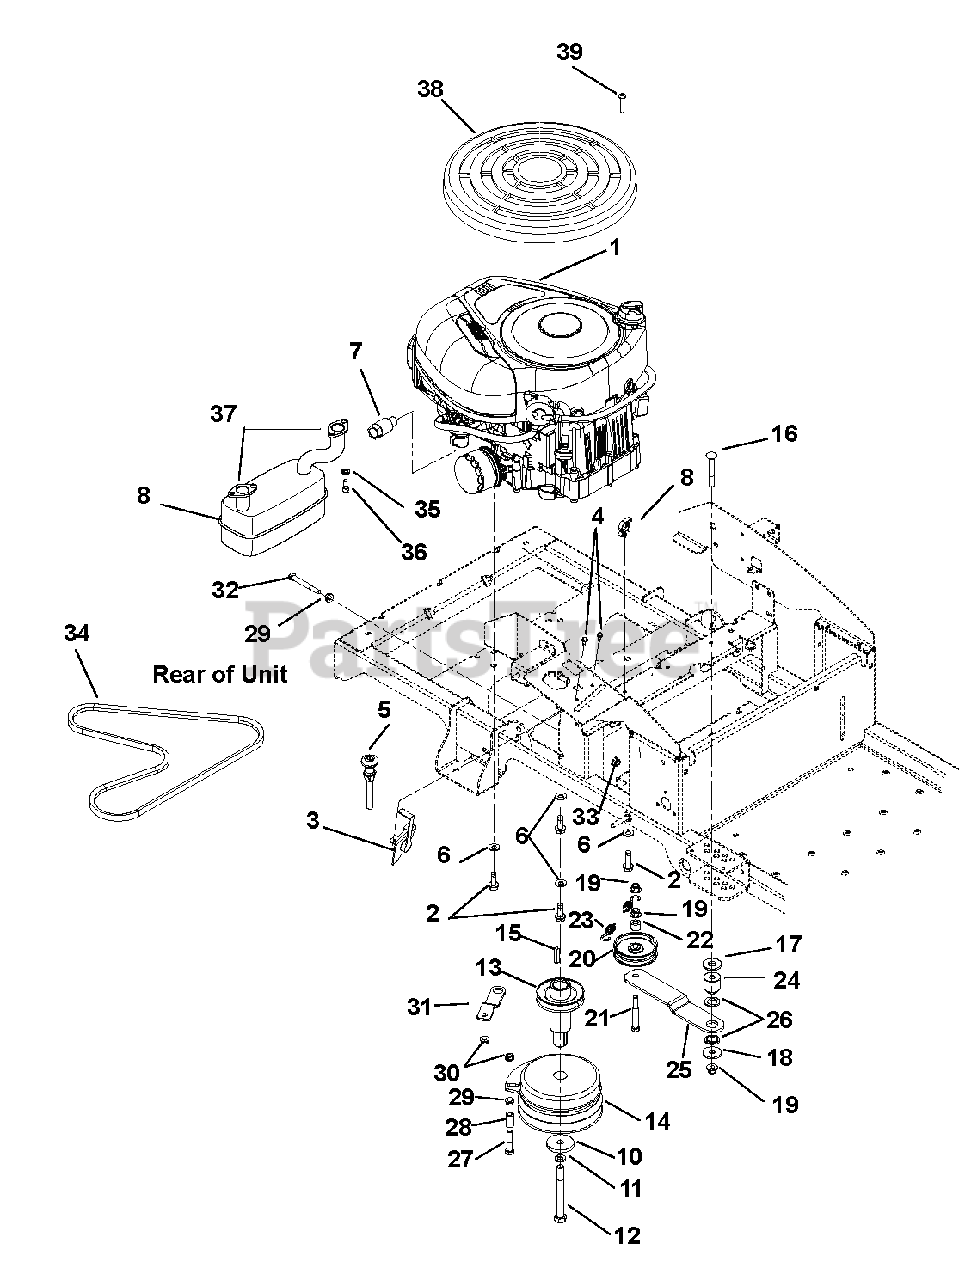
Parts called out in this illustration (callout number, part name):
1	ENGINE, 16HP V-TWIN CE
2	@SCR-TAP .38-16X1.00 HWH TR YZ
3	CABLE, THROTTLE
4	@SCR-TAP 10-24X.50 HWH TR YWZC
5	CABLE, CHOKE (SNAP IN)
6	@WSHR-FL-STL.406X.812X.065 YWZ
7	DRAIN, OIL
8	WIRE CLIP
9	MUFFLER - TWIN BRIGGS
10	WSHR-FL-STL .469X2.00X.25 YWZC
11	@WSHR-LK .44X.109 REG YWZC
12	BLT-HEX .44-20X4.50 GR8 YWZC
13	WMT-PTO EXTENSION W/SHEAVE
14	CLUTCH, 105 FT*LB MONO POLE
15	KEY-SQ .25 X 1.25 X .25 SAE
16	@BLT-RDHDSQNK .38-16X2.75 G5YZ
17	@WSHR-FL-STL.563X1.38X.109YWZC
18	WSHR-FL-STL .406X1.375X.135 YZ
19	@NUT-LK-NYL-FLG .38-16 YWZC
20	PULLEY, ENGINE CLUTCH 03608
21	@BLT-HEX .38-16X2.75 GR5 YWZC
22	BSHG-SLV .391X.688X.52 PM
23	SPRING, EXTENSION
24	SPACER, GROUND DRIVE IDLER
25	IDLER ARM, GROUND DRIVE
26	BUSHING, IDLER ARM
27	SCR-CAP .31-18X1 3/4 S/HD YWZC
28	SPACER, RUBBER 5/16 IDX1.0 LG
29	@NUT-SPNLK-FLG .312-18 YWZC
30	@NUT-LK-TOP-FLG .31-18 YWZC
31	BRKT, CLUTCH STOP
32	@BLT-HEX .31-18X2.75 GR5 YWZC
33	@NUT-LK-NYL-FLG .31-18 YWZC
34	V-BELT, HA-RAW EDGE
35	@WSHR-LK .31X.078 REG YWZC
36	SCR-CAP .31-18X.75 S/HD
37	GASKET, MUFFLER COURAGE TWIN
38	GUARD, BRIGGS ENGINE
39	SCREW, 8-16X.87 PHPAN 3 LOBE
